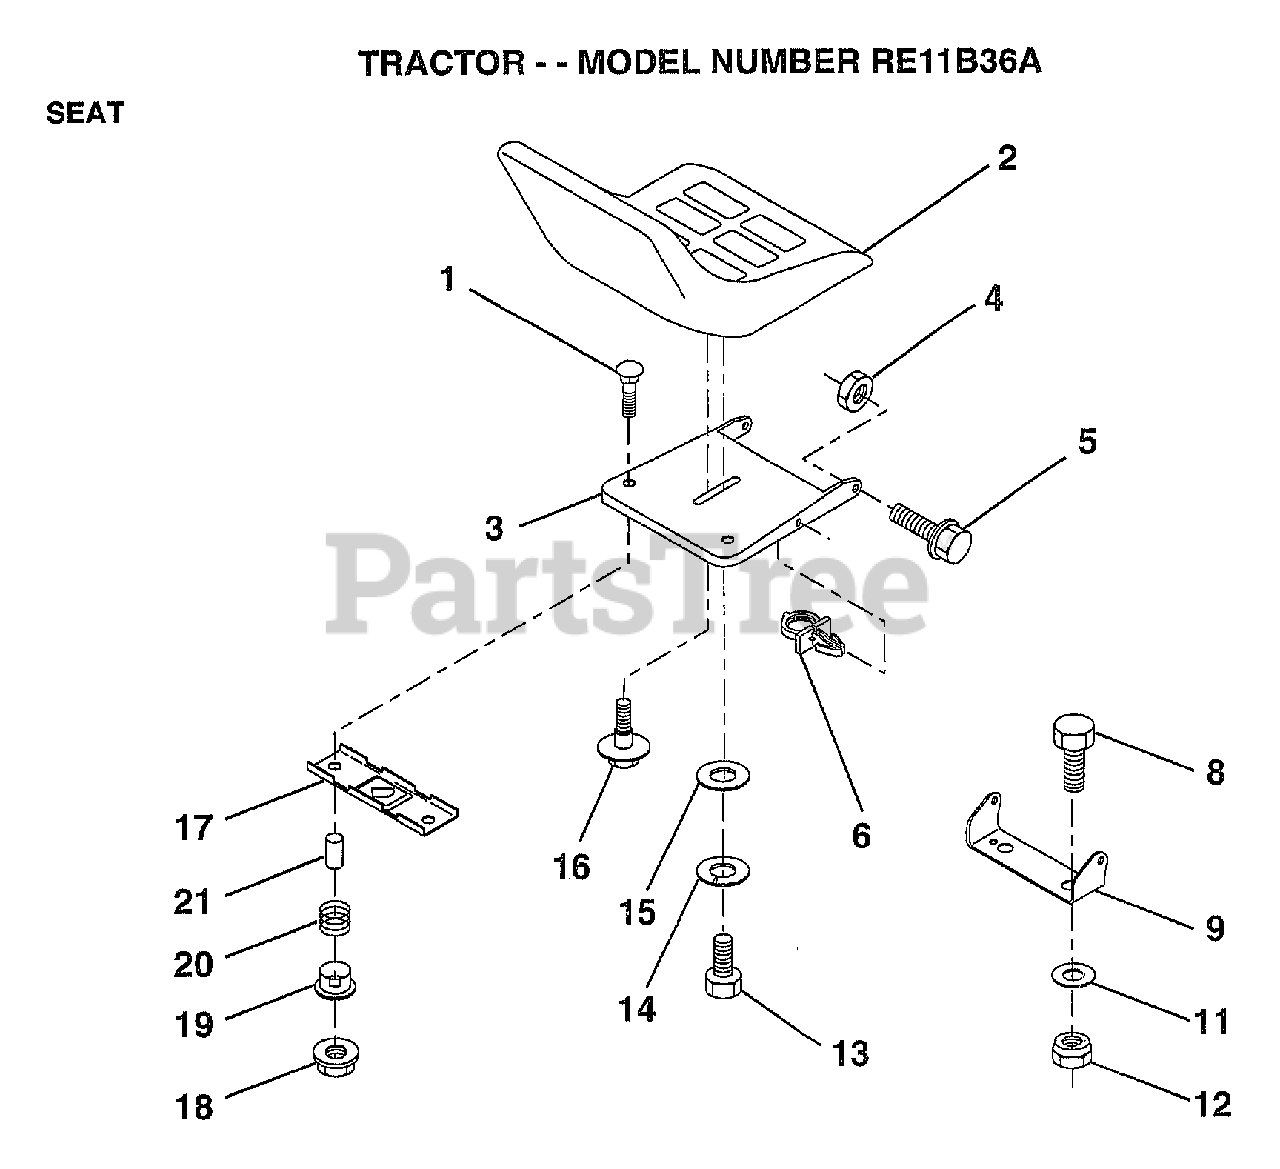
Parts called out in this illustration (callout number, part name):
1	BOLT-RD HD SQ NK
3	PAN-SEAT
4	NUT
5	"BOLT,SHOULDER"
6	CLIP.PUSH-IN.HING
8	BOLT
9	BRACKET PVT SEAT
11	WASHER
12	NUT
13	BOLT
14	LOCKWASHER
15	WASHER
16	"BOLT,SHOULDER"
17	BRKT SWITCH
19	BUSHING
20	SPRING
21	SPLIT SPACER
